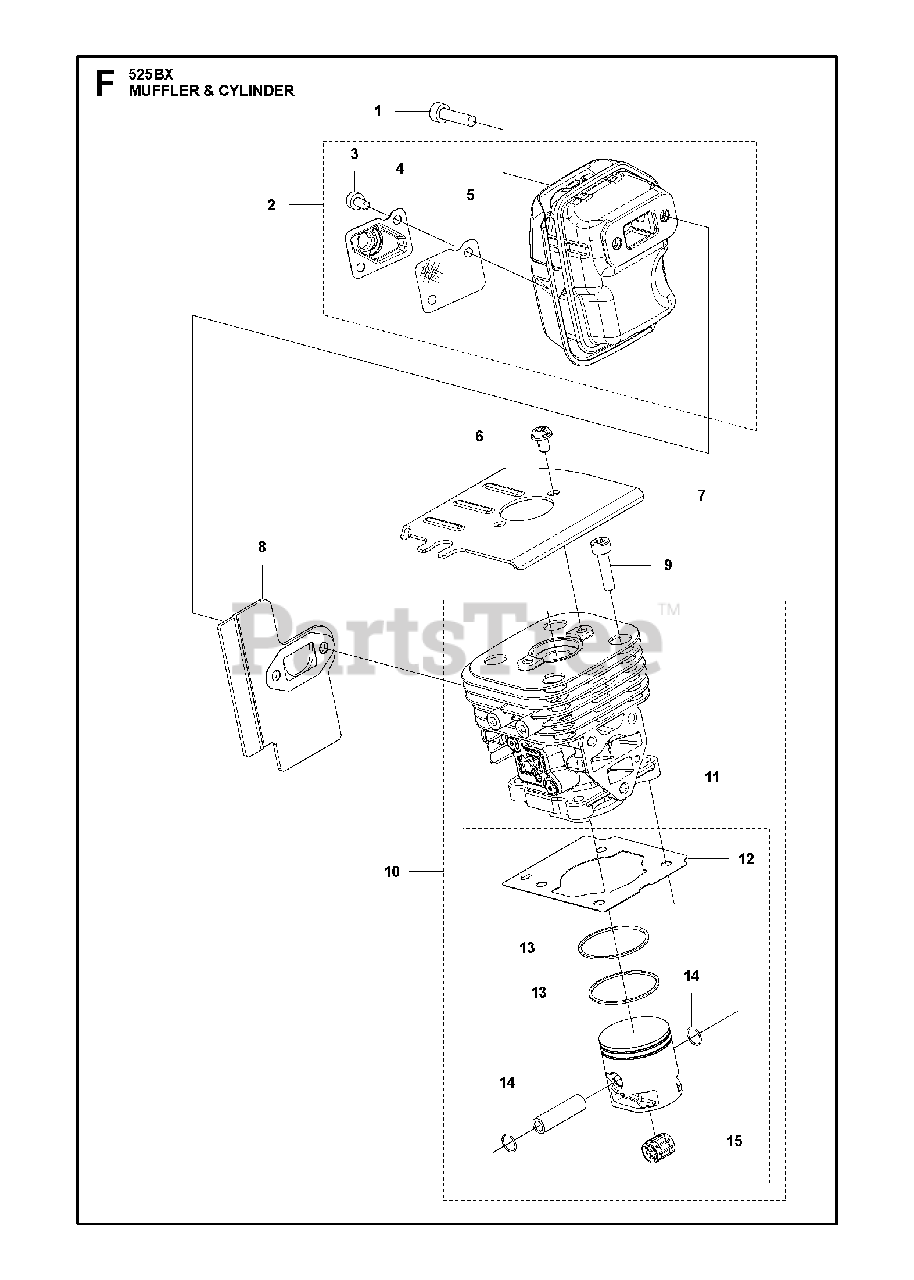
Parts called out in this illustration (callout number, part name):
1	BOLT
2	MUFFLER ASSY
3	BOLT
4	EXHAUST COVER
5	SPARK ARRESTER
7	PLATE CYLINDER
8	GASKET MUFFLER
9	BOLT
10	KIT CYLINDER & PISTON
11	KIT PISTON
12	GASKET BASE
13	RING
14	RING
15	BEARING
